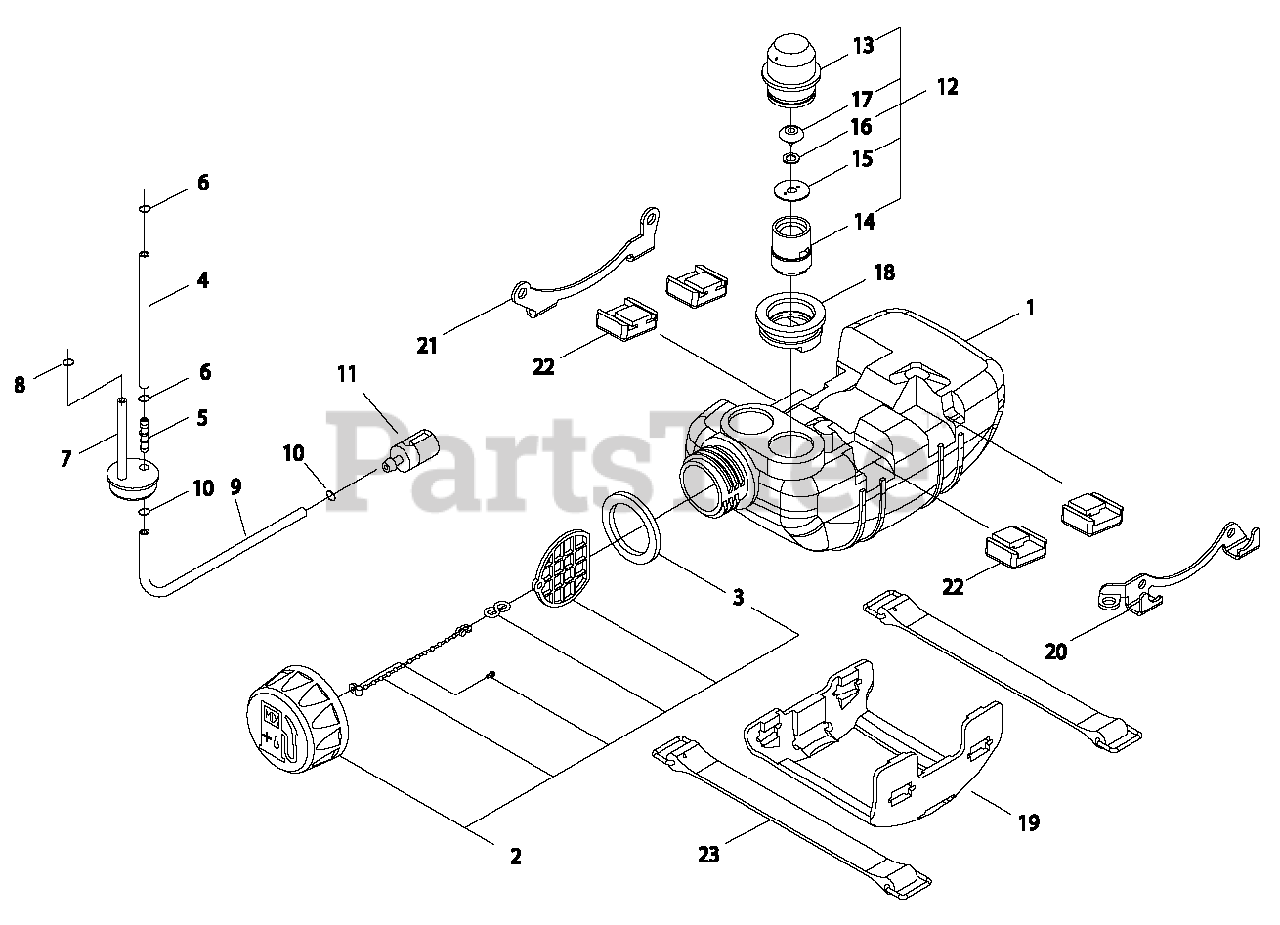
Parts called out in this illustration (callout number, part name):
1	TANK, FUEL
2	CAP ASSY, FUEL
3	GASKET, FUEL CAP
4	PIPE, FUEL
5	CONNECTOR, PIPE
6	CLIP Ø6
7	GROMMET, FUEL W/ PIPE
8	CLIP Ø6
9	PIPE, FUEL
10	CLIP Ø6
11	FILTER ASSY, FUEL
12	VENT ASSY
13	CAP, VENT
14	HOLDER, VENT
15	RETAINER
16	WASHER
17	VENT ASSY
18	GROMMET, VENT
19	GUARD, FUEL TANK
20	BRACKET S
21	BRACKET M
22	CUSHION, FUEL TANK
23	STRAP, FUEL TANK
